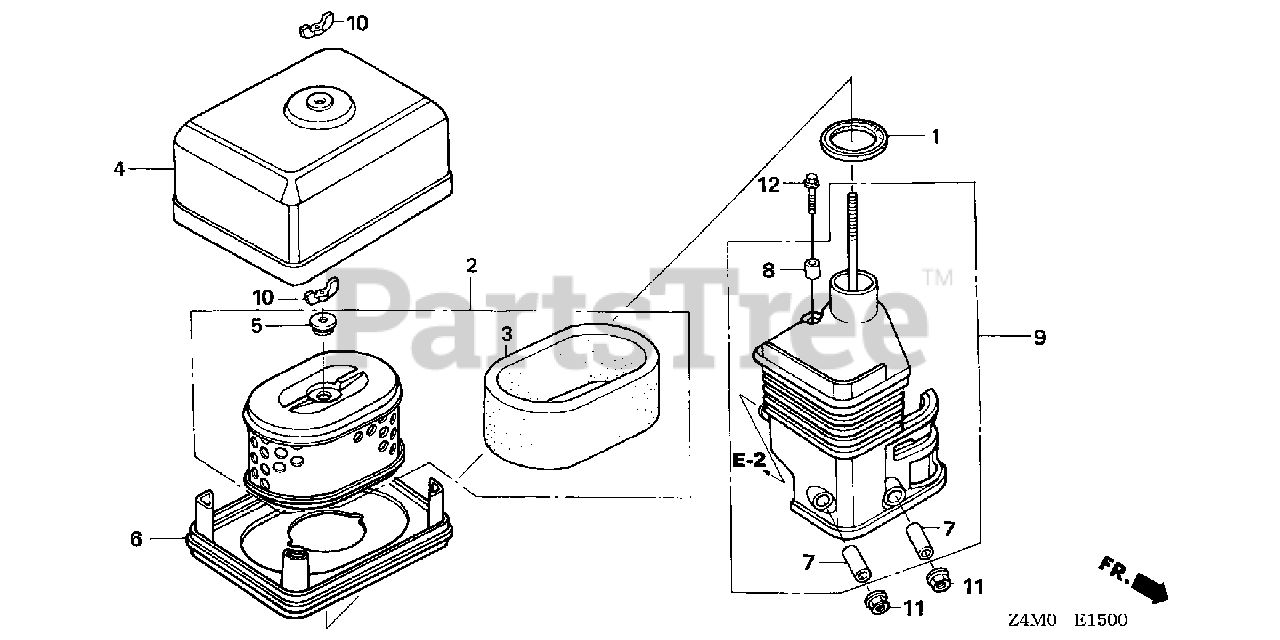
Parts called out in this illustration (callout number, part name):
1	GASKET, ELBOW
2	ELEMENT, AIR CLEANER (DUAL)
3	FILTER (OUTER)
4	COVER, AIR CLEANER (DUAL)
5	GROMMET, AIR CLEANER
6	NOSE, MUFFLER
7	COLLAR, AIR CLEANER
8	COLLAR B, AIR CLEANER
9	ELBOW, AIR CLEANER
10	WINGNUT, TOOL BOX SETTING
11	NUT, FLANGE (6MM)
12	BOLT, FLANGE (6X20)
